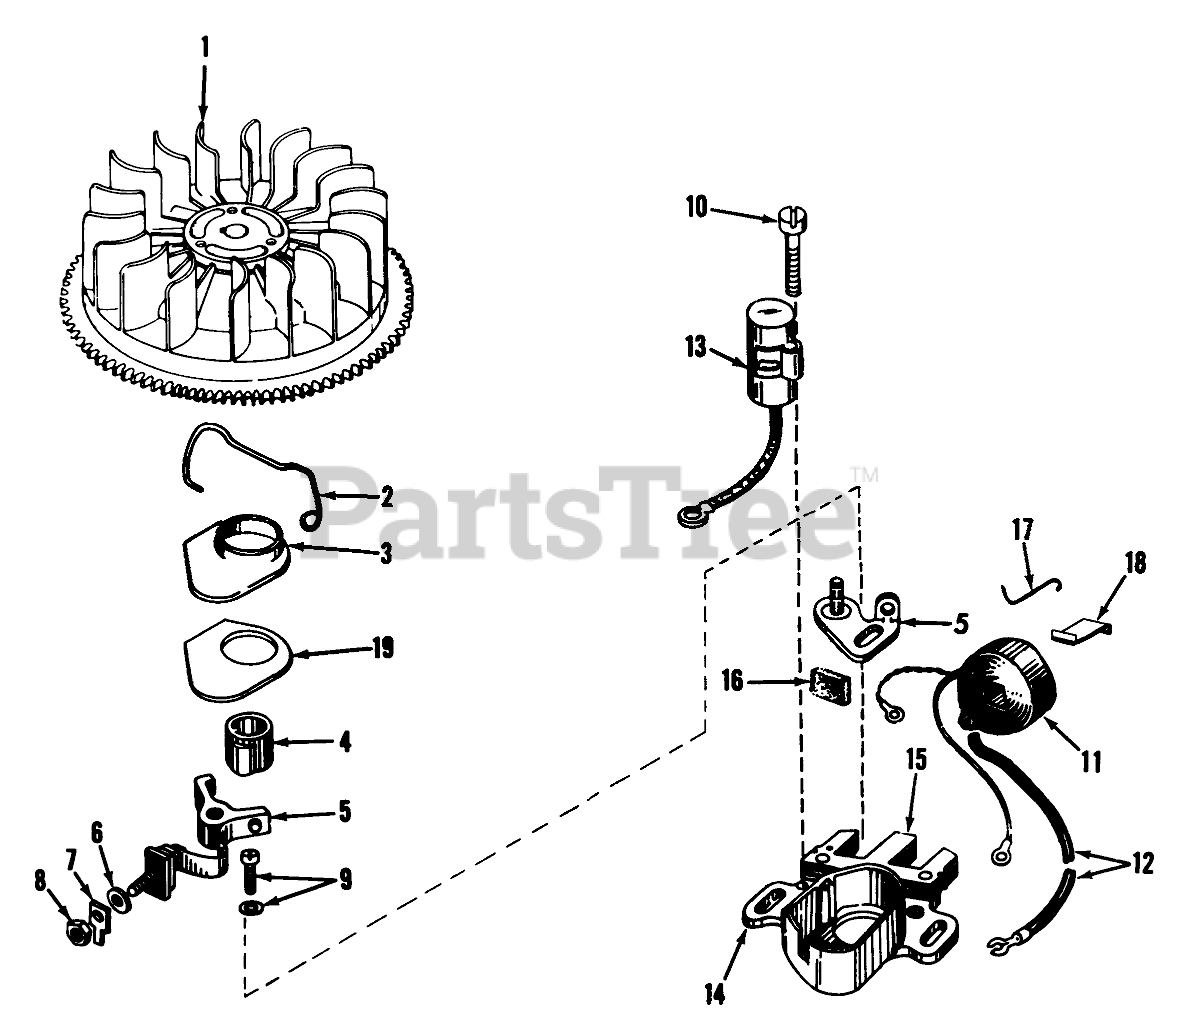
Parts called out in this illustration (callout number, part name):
1	Flywheel
2	Spring Breaker Box
3	Cover, Dust
4	Cam-Breaker
5	Breaker Assy.
7	Terminal
9	Breaker Screw
10	Condenser Screw
11	Coil Assy., (Incl. No. 12)
12	Wire, Lead
13	Condenser
14	Core & Plate
15	Stator Assy., (Incl. Nos. 2, 3, 5 thru 14 & 16 thru 19)
16	Felt,Cam Wiper
17	Clip, Coil
18	Spring Coil Wedge
19	Gasket, Dust Cover
